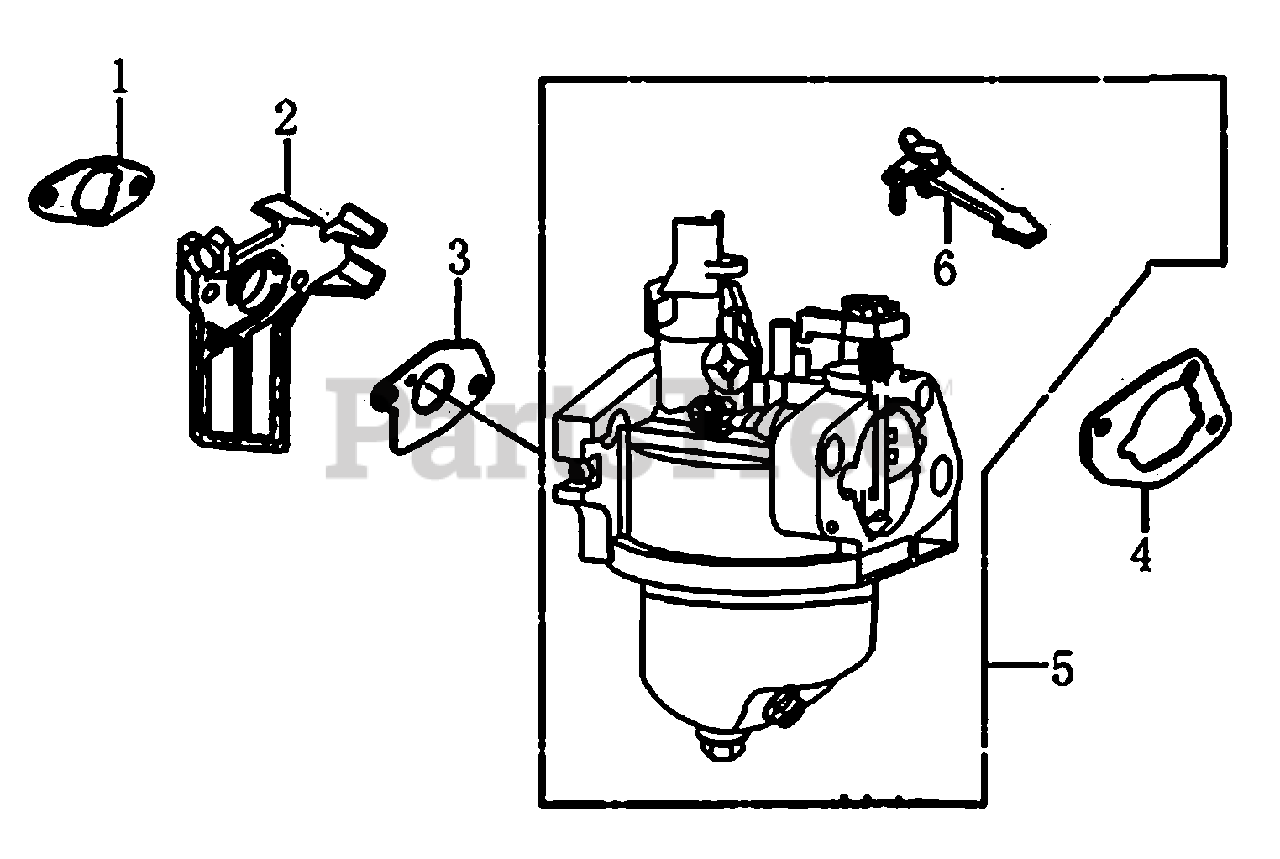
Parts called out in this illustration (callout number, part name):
1	GASKET, INSULATOR
2	INSULATOR, CARBURETOR
3	GASKET, CARBURETOR
4	GASKET, AIR CLEANER
5	CARBURETOR
6	LEVER ASSY, CHOKE
